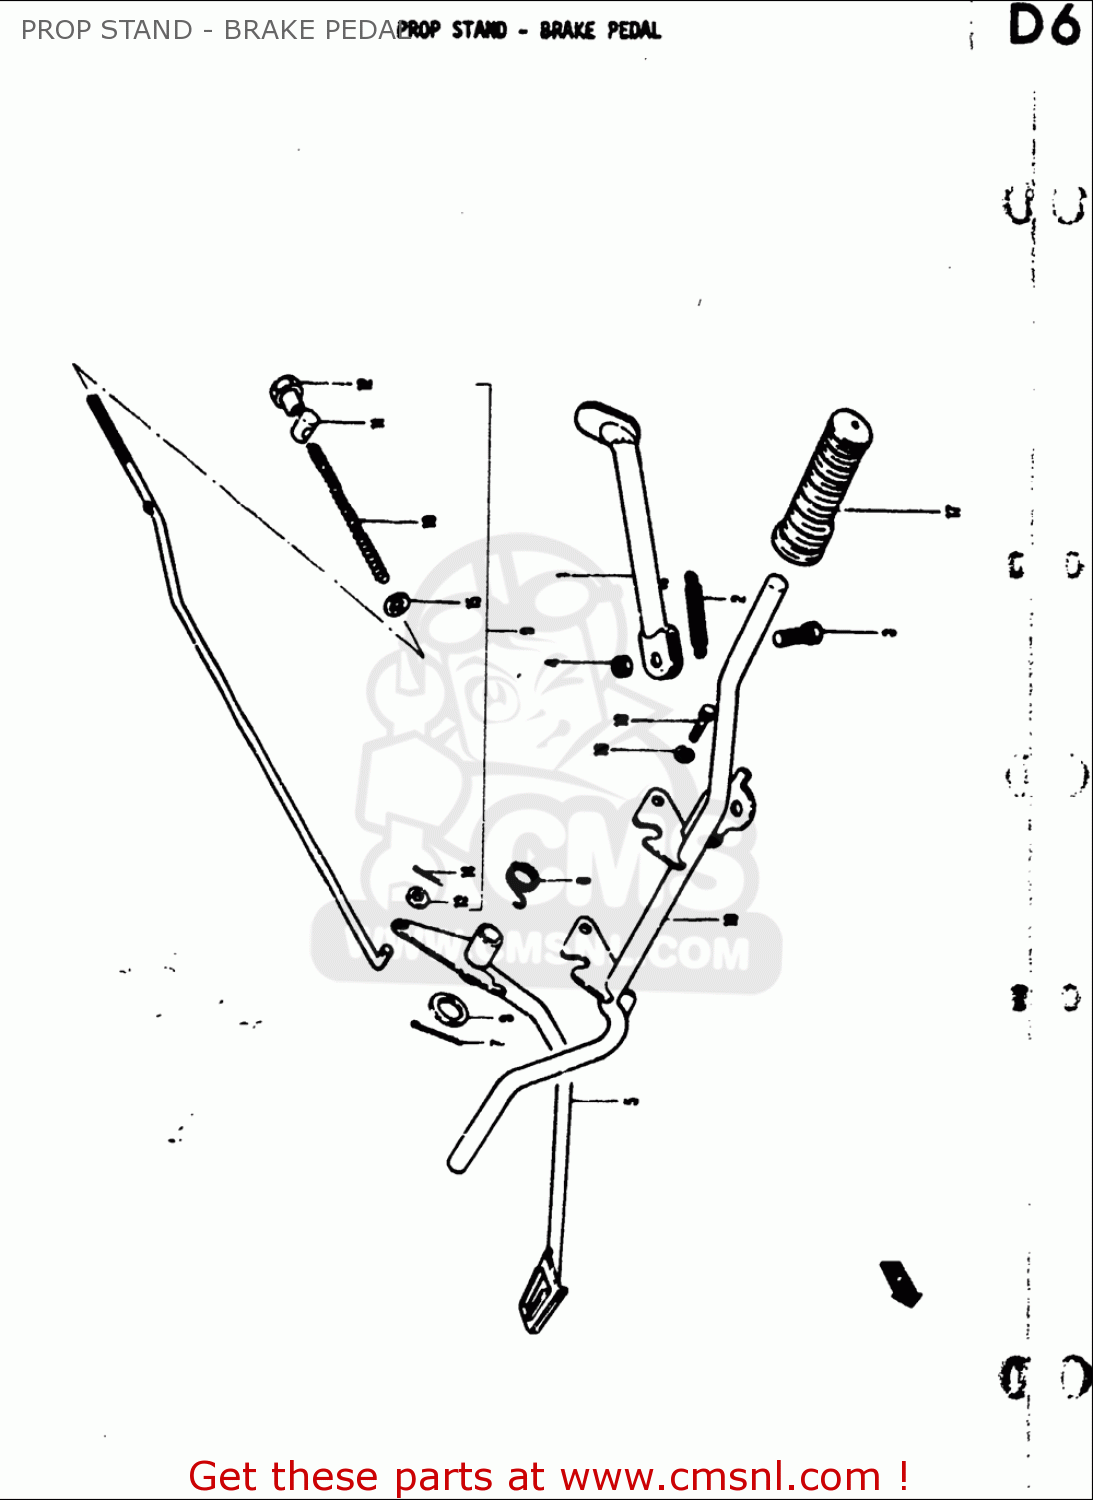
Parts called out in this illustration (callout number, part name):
2	SPRING
3	BOLT(10X30)
4	NUT
6	SPRING
7	PIN
8	WASHER(15.5X26X2.3)
9	ROD ASSEMBLY,REAR BRAKE
10	SPRING
11	PIN(11X18)
12	NUT
13	WASHER
14	PIN
15	WASHER
17	RUBBER,FR FOOTREST
18	BOLT
19	WASHER,LOCK
